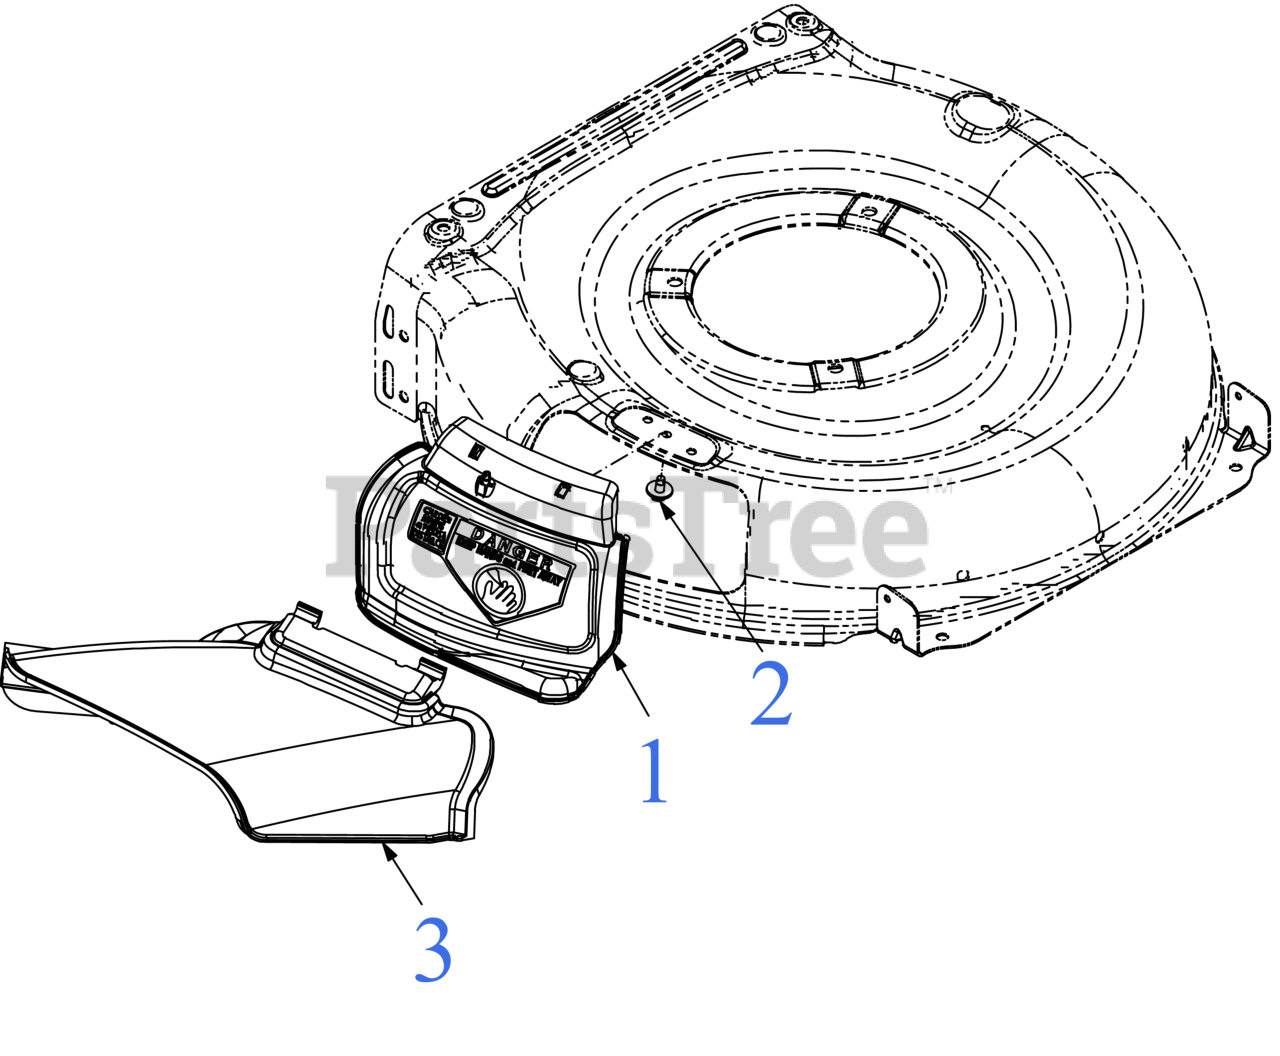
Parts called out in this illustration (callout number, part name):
1	21" MULCH PLUG (HINGED)
1	TORSION SPRING
1	CHUTE DEFLECTOR BRACKET
1	HINGE PIN
2	SCREW 1/4-20 x .50
3	SIDE DISCHARGE CHUTE
